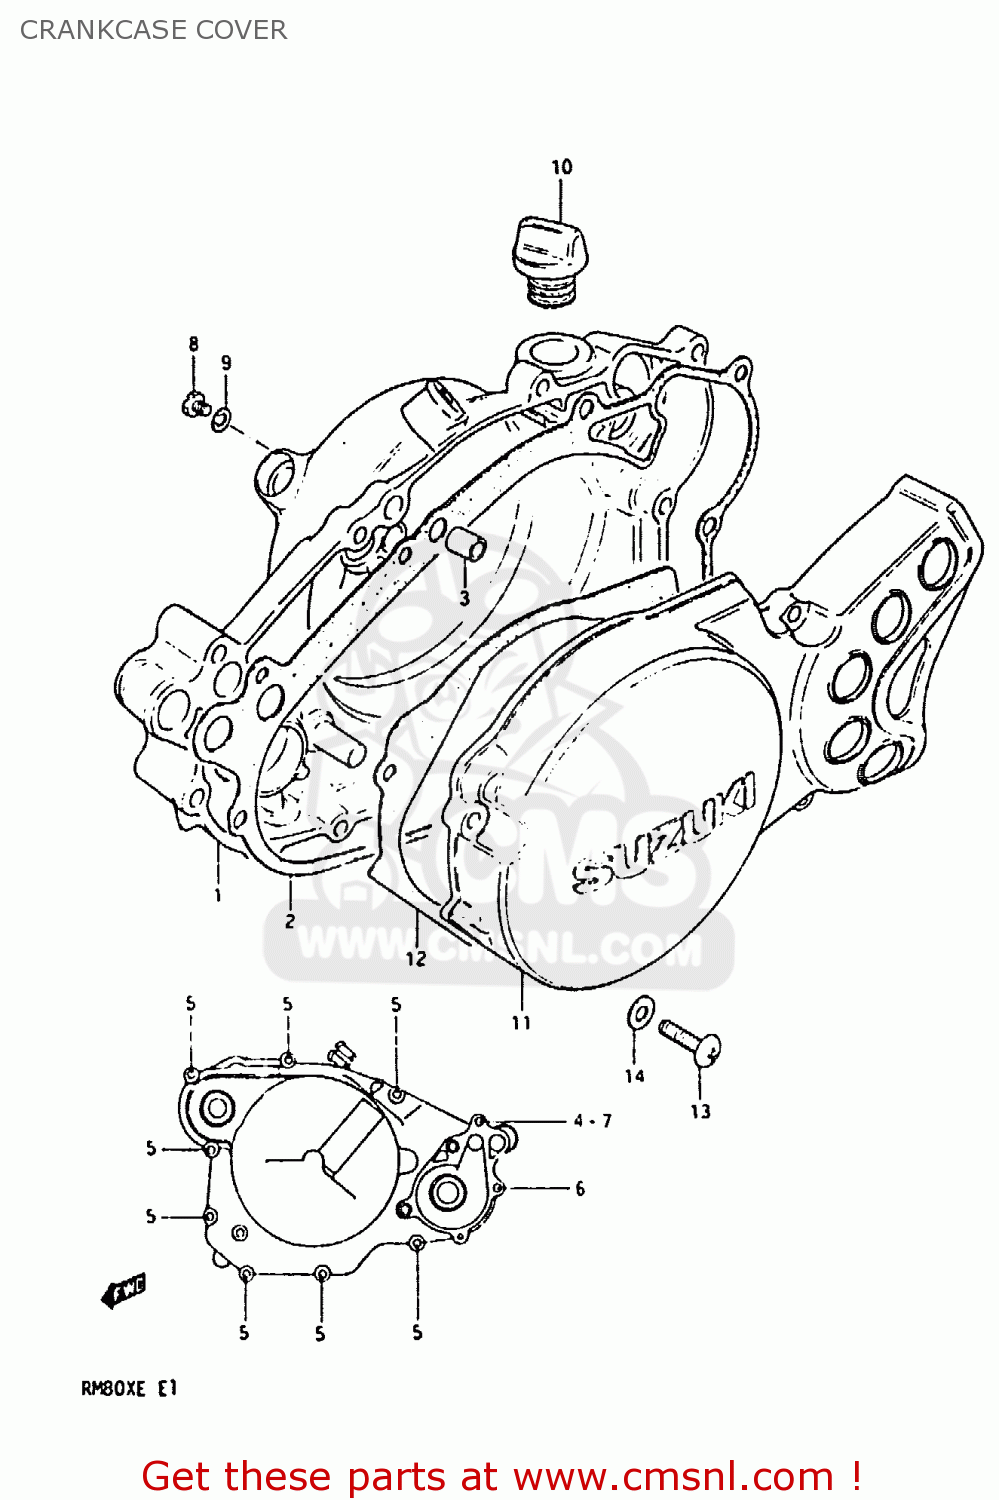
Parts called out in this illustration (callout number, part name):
1	COVER,CLUTCH
2	GASKET,CLUTCH COVER (MCA)
3	PIN
4	WASHER
5	SCREW
6	SCREW
7	SCREW
8	SCREW(6X10)
9	GASKET(6.2X11X1) (NAS)
10	PLUG
11	COVER,MAGNETO
12	GASKET,MAGNETO COVER (NAS)
13	SCREW 5X20
14	WASHER,5MM
